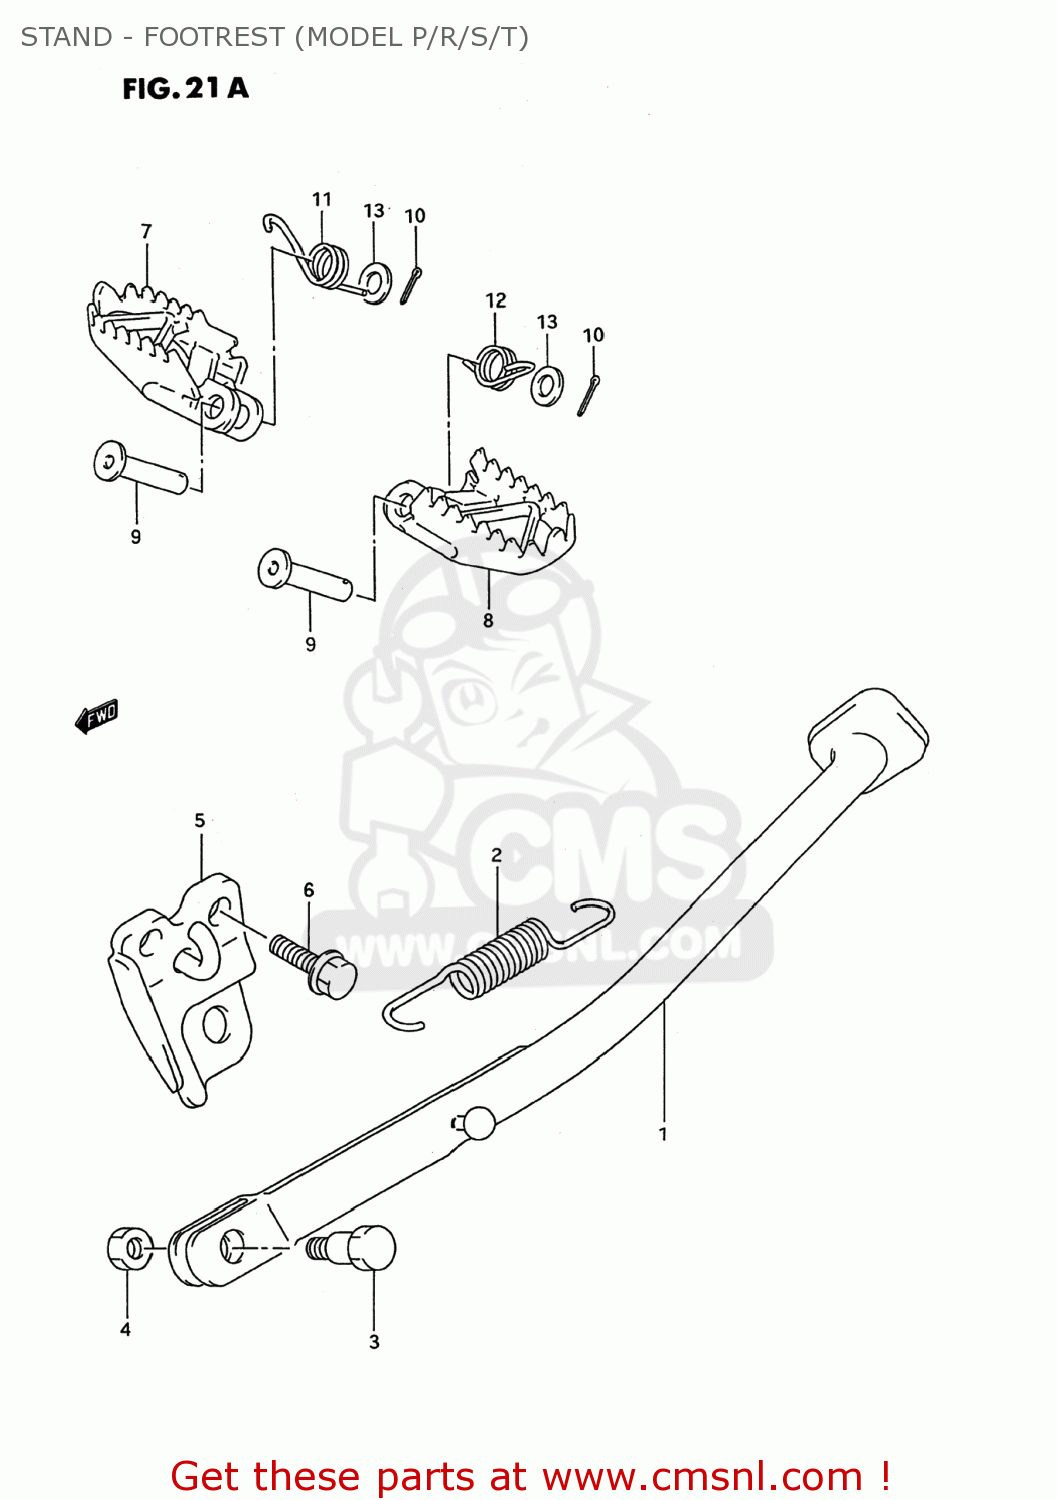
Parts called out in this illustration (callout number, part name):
1	STAND,PROP(SILVER)
2	SPRING
3	BOLT(10X30)
4	NUT
5	BRACKET,PROP STAND
6	BOLT(10X25)
7	FOOTREST,R
8	FOOTREST,L
9	PIN(10X41.5)
10	PIN 25X20
11	SPRING
12	SPRING
13	WASHER
